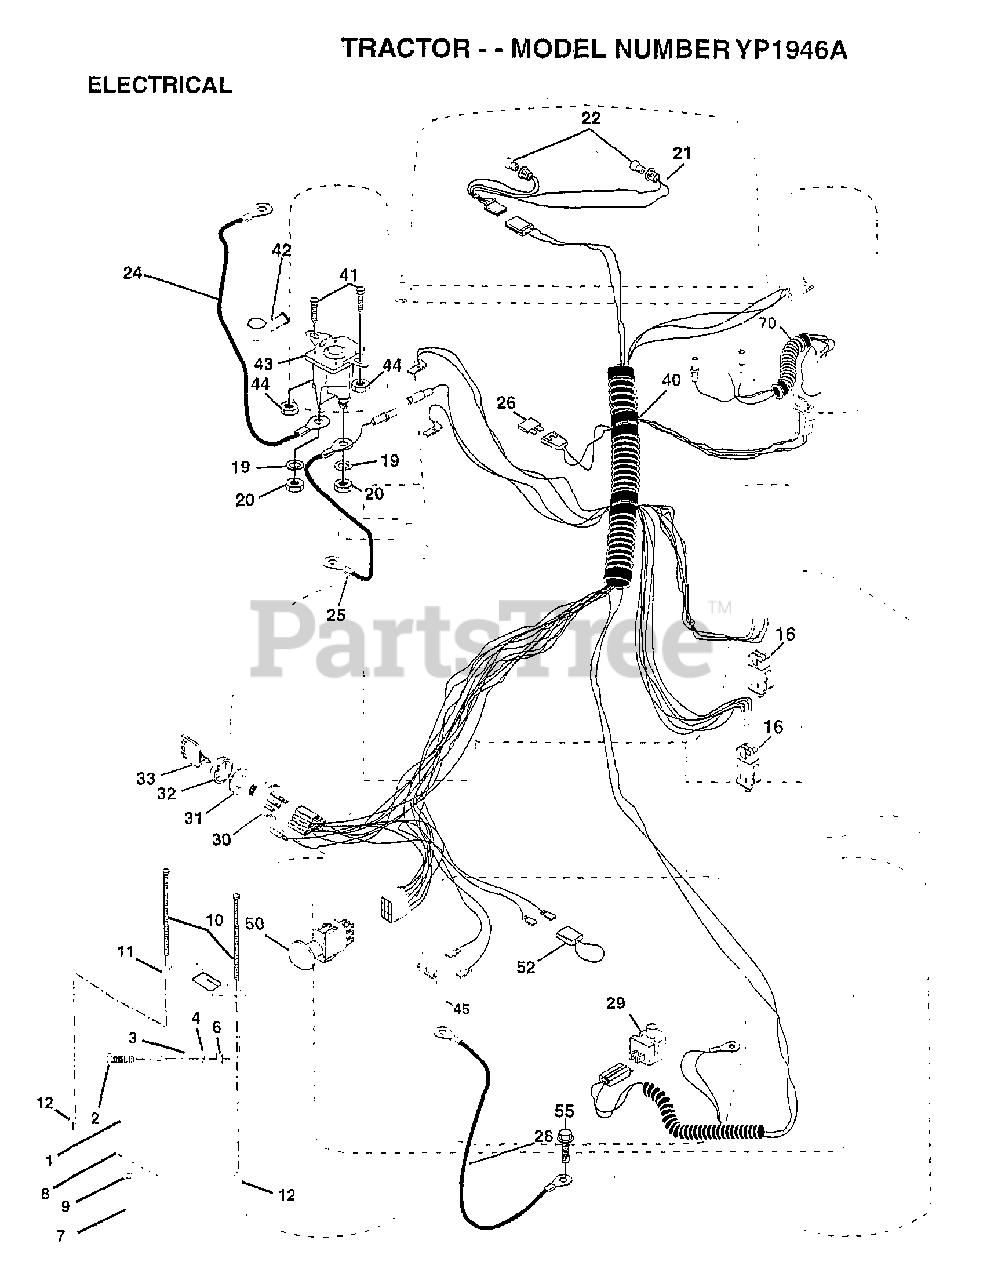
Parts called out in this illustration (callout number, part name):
2	BOLT LT
3	WASHER
4	LOCKWASHER
7	"DRAIN TU T, BATT"
8	"TRAY T, BATTERY"
9	HOSE CLAMP T
11	HOLDDOWN BATTERY
16	SWITCH INTERLOCK
20	NUT
21	"HARNESS,LIGHT SOC"
22	HEADLAMP BULB
24	"CABLE T, BATTERY"
25	CABLE.6GA.22W/16W
26	FUSE HYT
28	CABLE.GRND.6GA.21
29	SWITCH SEAT
30	SWITCH IGN 4POS
31	NUT IGNITION
32	COVER KEY SWITCH
33	KEY
40	HARNESS IGNITION
41	BOLT HXHD FIN
44	NUT HXKEP 1/4X20
45	AMMETER
50	PTO SWITCH.BLK
52	PROTECTION LOOP
55	SCREW LT
70	HARNESS ENG B&S
